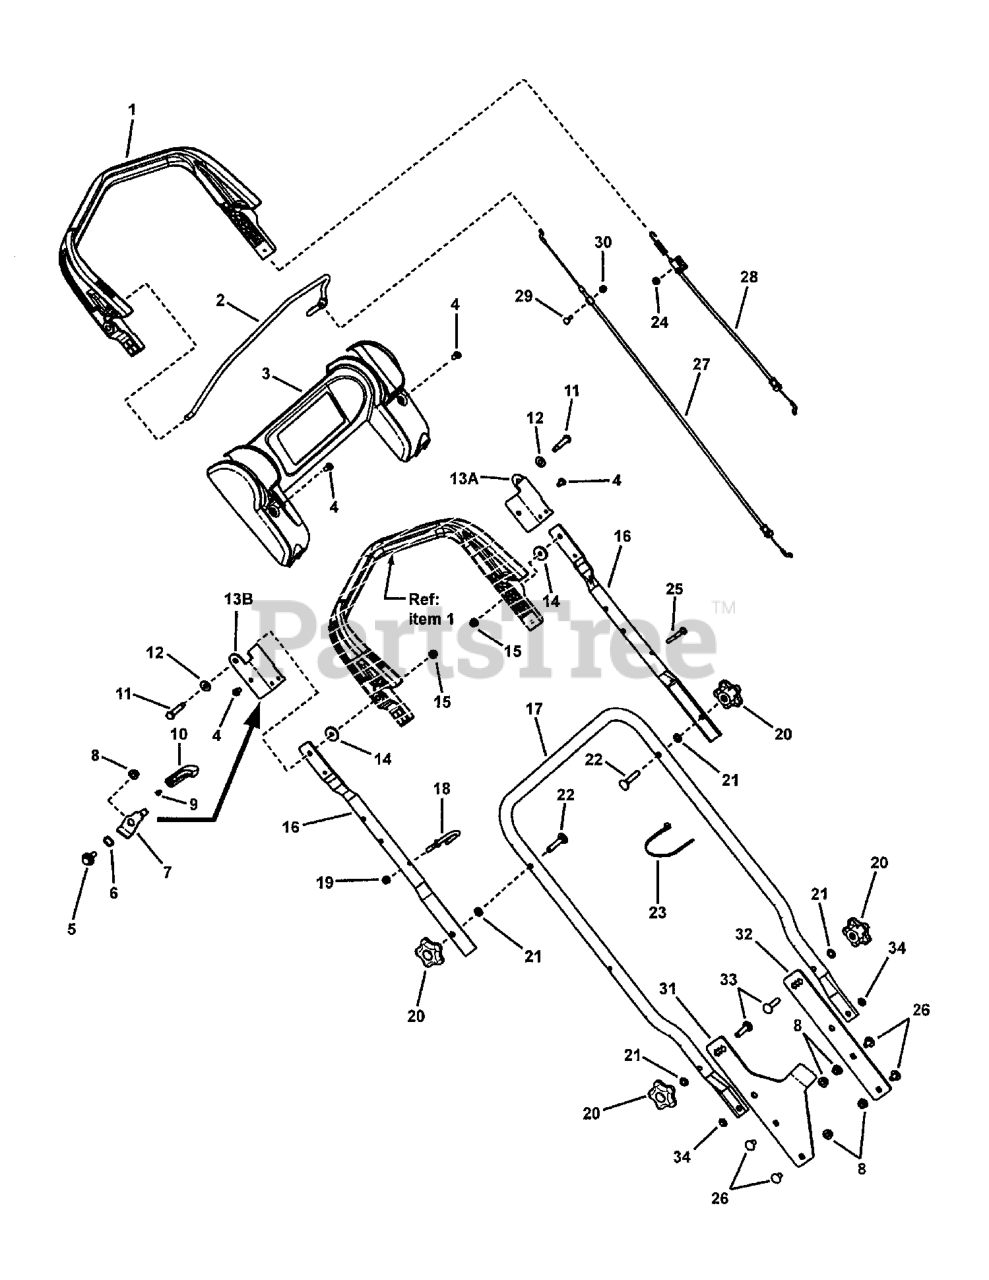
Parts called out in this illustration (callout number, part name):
1	HANDLE, PIVOTING - DEERE WALK
2	BAIL, PIVOTING HANDLE - 21" JD WBM
3	PANEL, UPPER HANDLE, DEERE
4	TORX ST, 1/4-20 X .550
5	IDLER PIVOT BOLT
6	WASHER, .531 X .781 3 - WAVE
7	HANDLE, LOCK
8	FLN, 5/16-18 YZ
9	RIVET, PLASTIC SNAP
10	THROTTLE CONTROL LEVER
11	BOLT, SHOULDER, 5/16 X 2.500, YZ
12	SHIM WASHER, 5/16 I.D.
13A	BRACKET, LH, ROTATION LIMIT
13B	BRACKET, RH, ROTATION LIMIT
14	WASHER, FLAT, 1" OD X .387 ID
15	NUT, HEX FLANGE, 1/4-20, ESNA, YZ
16	HANDLE, UPPER, STRAIGHT, EASY LINE
17	HANDLE, LOWER, JS45
18	GUIDE, ROPE
19	HN, 1/4C NYL RNG
20	KNOB, HANDLE, 5 PRONG
21	ITLW, 5/16
22	CHSNB, 5/16-18 X 2 GR2
23	WIRE TIE, 11 INCH STD BLK NYLON
24	HCLN, 1/4-20
25	HHCS, 1/4CX1-3/4
26	RHSSNB, 5/16-18X3/4
27	CABLE, CONTROL, ZONE
28	CABLE, DRIVE, PIVOT HANDLE, EASY LINE
29	RHSNB, 10-24X3/4, YZ
30	HLN, 10-24 UNC-2B W/NYLON INSERT
31	BRACKET, LOWER HANDLE - RH
32	BRACKET, LOWER HANDLE
33	RHSNB, 5/16-18 X 1-1/2 YZ
34	LHCLN, 5/16-18- BLACK
